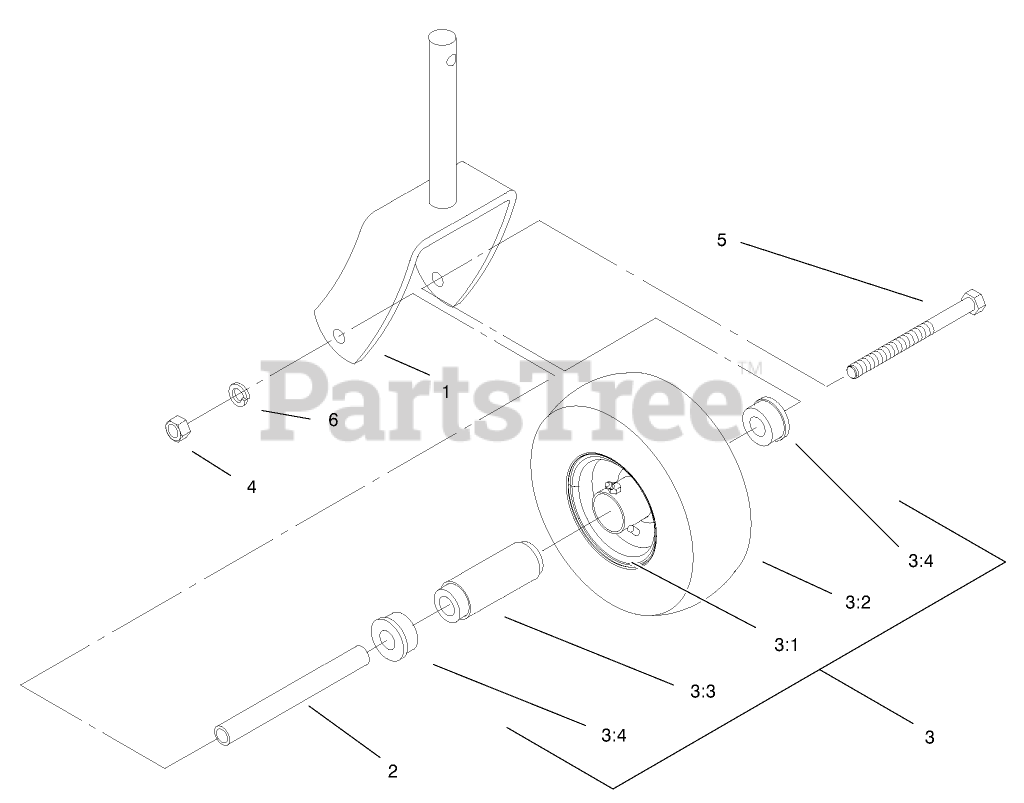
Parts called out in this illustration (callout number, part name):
1	FORK
2	SPACER
3	WHEEL AND TIRE ASM
3:1	Rim
3:2	Tire
3:3	BEARING
3:4	BUSHING
4	NUT-HH
5	SCREW-HH
6	WASHER-LOCK
